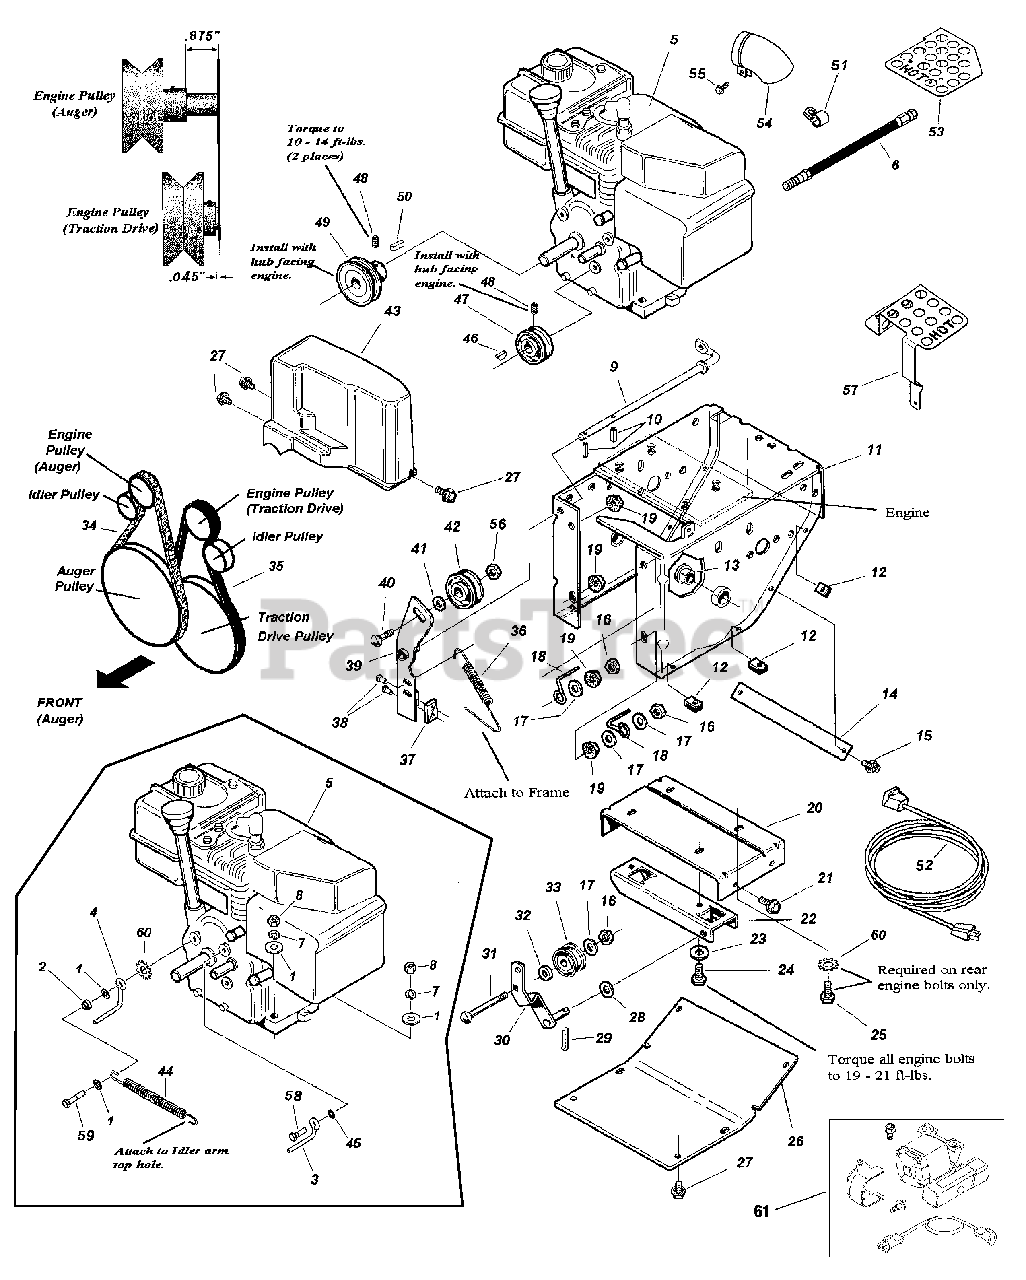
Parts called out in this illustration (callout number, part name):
1	WASHER, 5/16" Flat
2	BUSHING, Differential Link
3	BELT GUIDE, LH, Traction Drive Belt
4	BELT GUIDE, RH, Traction Drive Belt
5	ENGINE, 7-1/2HP Briggs OHV
5	ENGINE, 7-1/2HP Briggs OHV Euro
5	ENGINE, 8-1/2HP Briggs Intek Mod 15 ES
5	ENGINE, 8-1/2HP Briggs Intek Mod 15 Manual
6	HOSE, Oil Drain
7	WASHER, 5/16" Split Lock
8	NUT, 5/16-18 Hex, GR 5 or B
10	ROLL PIN, 3/16 x 3/4"
11	WELDMENT, Intermediate Frame- Orange
12	SPEED NUT, 1/4-20 U-Type
13	BUSHING, 1.00 long
14	SUPPORT, Tie Bar
15	SCREW, #10-24 x 1/2" Hex Washer Self-Tap
16	JAM NUT, 3/8-16 Hex Center Lock
17	WASHER, 3/8" SAE Flat
18	ROD, Belt Guide
19	NUT, 3/8-16 Hex Nyloc
20	SUPPORT, Frame
21	SCREW, 5/16-18 x 1/2" Hex Washer Self-Tap
22	SUPPORT, Pivot
23	WASHER, 5/16" Flat
24	CAPSCREW, 5/16-18 x 1-3/4 Hex Head, G5
25	SCREW, 5/16-18 x 2" Hex Head Cap, GR 5
26	COVER, Bottom- Orange
27	SCREW, 1/4-20 x 5/8" Hex Washer Self-Tap
28	WASHER, 7/16" Flat
29	COTTER PIN, 1/8 x 3/4"
30	WELDMENT, Idler Arm
31	BOLT, 3/8-16 x 1-1/4" Short Square Neck Carriage, GR 5
32	SPACER, .377 ID x .75 OD x .312 Long
33	PULLEY, Idler
34	V-BELT,
35	V-BELT,
36	SPRING, Extension
38	RIVET, Blind
39	ASSEMBLY, Idler Arm w/Brake Pad
40	BOLT, 3/8-16 x 1-3/4" Short Square Neck Carriage, GR 5
41	WASHER, 3/8" Flat (.41 ID x 1.00 OD x .13 Thick)
42	PULLEY, Idler
43	COVER, Belt
44	SPRING, Extension, .562 O.D. x 4.250 Long
45	WASHER, 5/16" Internal Tooth Lock
46	KEY - Hi Pro .125 x .625 HP 504 SAE1035
47	PULLEY, V Groove
48	SET SCREW, 5/16-18 x 5/16" Hex Recess, Cup Point
49	PULLEY, 2.75 OD
50	KEY, 3/16 Square x 1"
51	HARNESS CLIP
52	CORD, Electric Start
53	GUARD, Muffler
54	MUFFLER, Deflector- B&S
55	HEX SCREW, Thread Rolling M4 x 0.7
56	NUT, 3/8-16 Hex Flange Lock Two Way
57	HEAT SHIELD, 7.5HP B&S Powerbuilt Muffler
58	SCREW, 5/16-24 x 1" Hex Head Cap, GR 5
59	SCREW, 5/16-24 x 1-1/2" Hex Head Cap, GR 5
60	LOCKWASHER, 5/16" Exterior Tooth
61	KIT, Electric Start, 230 volt
